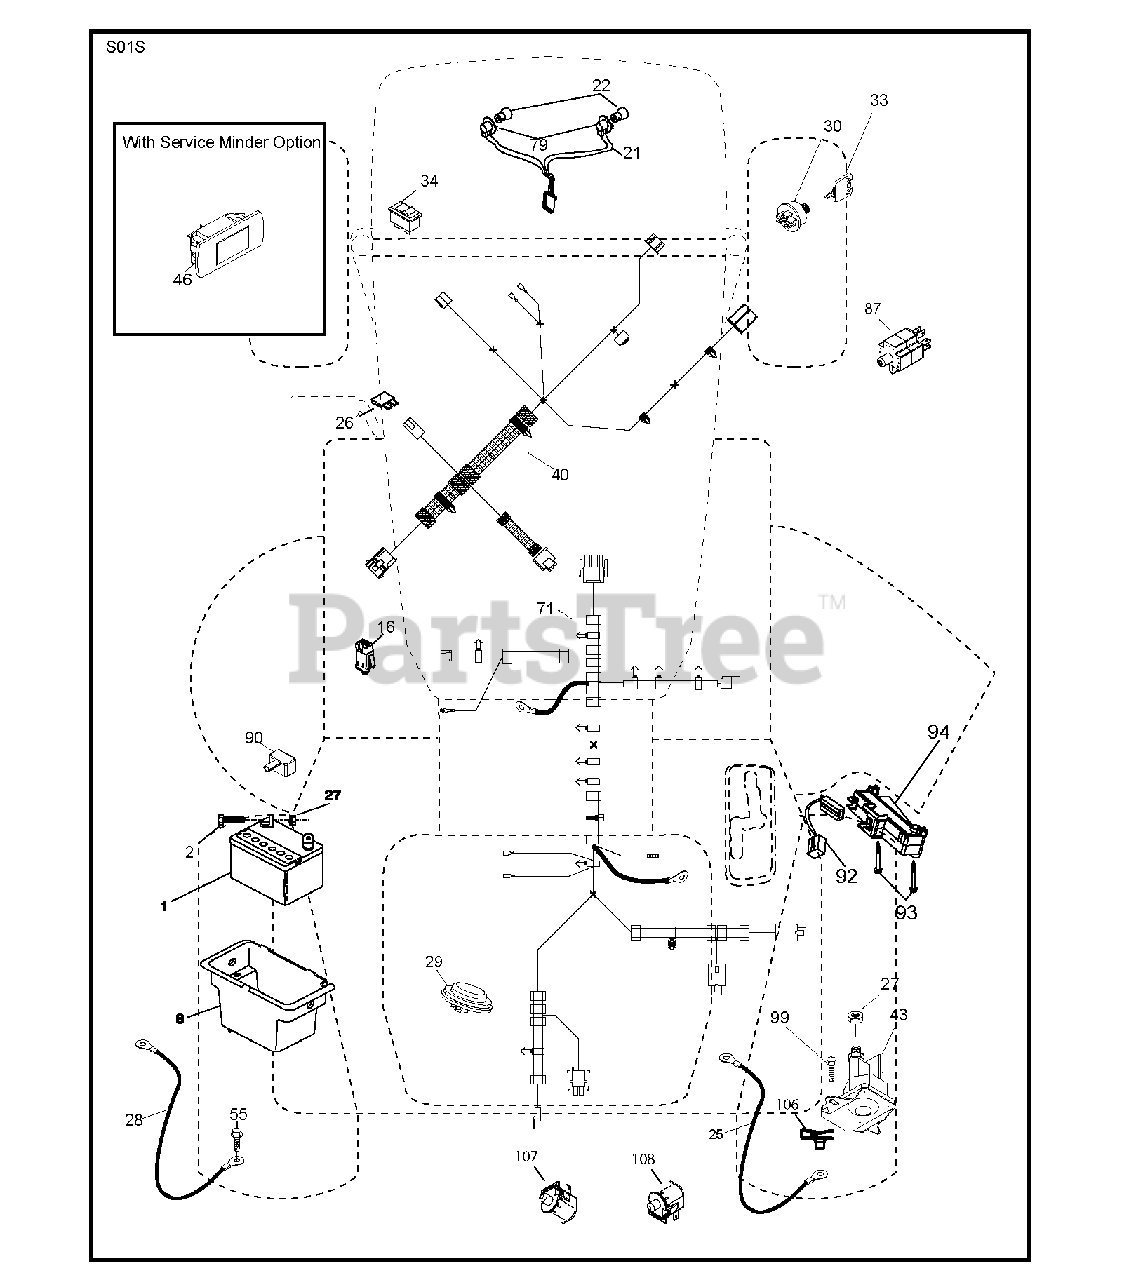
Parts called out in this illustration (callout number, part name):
16	SWITCH INTERLOOK PUSH-IN
21	HARNESS.LIGHT W/4152J BULBS
22	LIGHTBULB
25	CABLE.BATTERY.20.RED.8 AWG
26	FUSE 20AMP
27	NUT
29	SWITCH.SEAT.DELTA.OPC.
30	SWITCH.IGN.DELTA.W.LGH.ROS
33	KEY.CHAIN.BLISTER.PACK.GEN.INT
34	SWITCH LT
43	SOLENOID.W/BRASS.PLUNG
55	SCREW 5/16"
79	BULB HOLDER ASM.
90	COVER, TERMINAL BATTERY
92	HARNESS.PIGTAIL.CONSLE
93	SCREW.PLASTITE
94	MODULE.REVERSE.ROS
99	SCREW HEXWSHR 1/4-20X3/4
106	1/4-20 U NUT
108	SWITCH.SNAPMOUNT.NC
